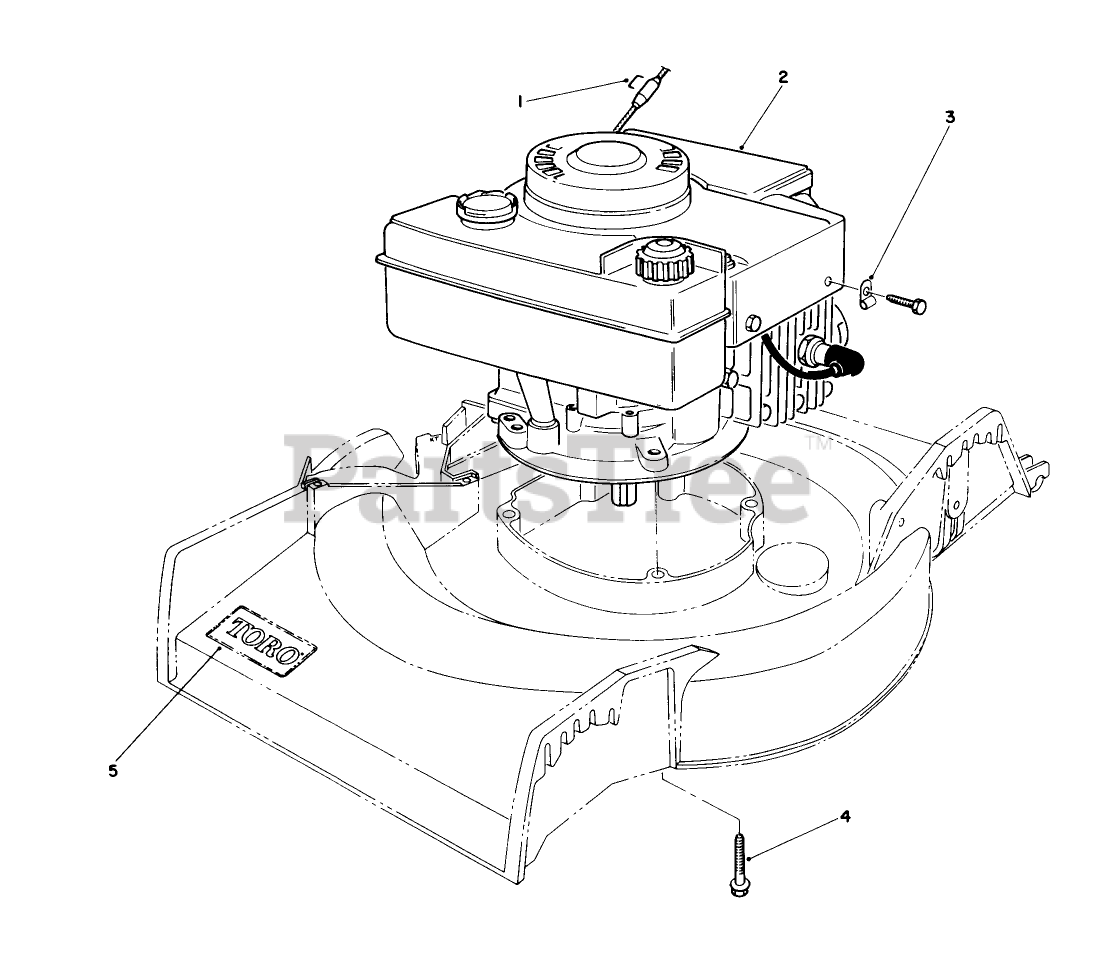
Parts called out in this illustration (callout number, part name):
1	Staple
2	Engine
5	DECAL
